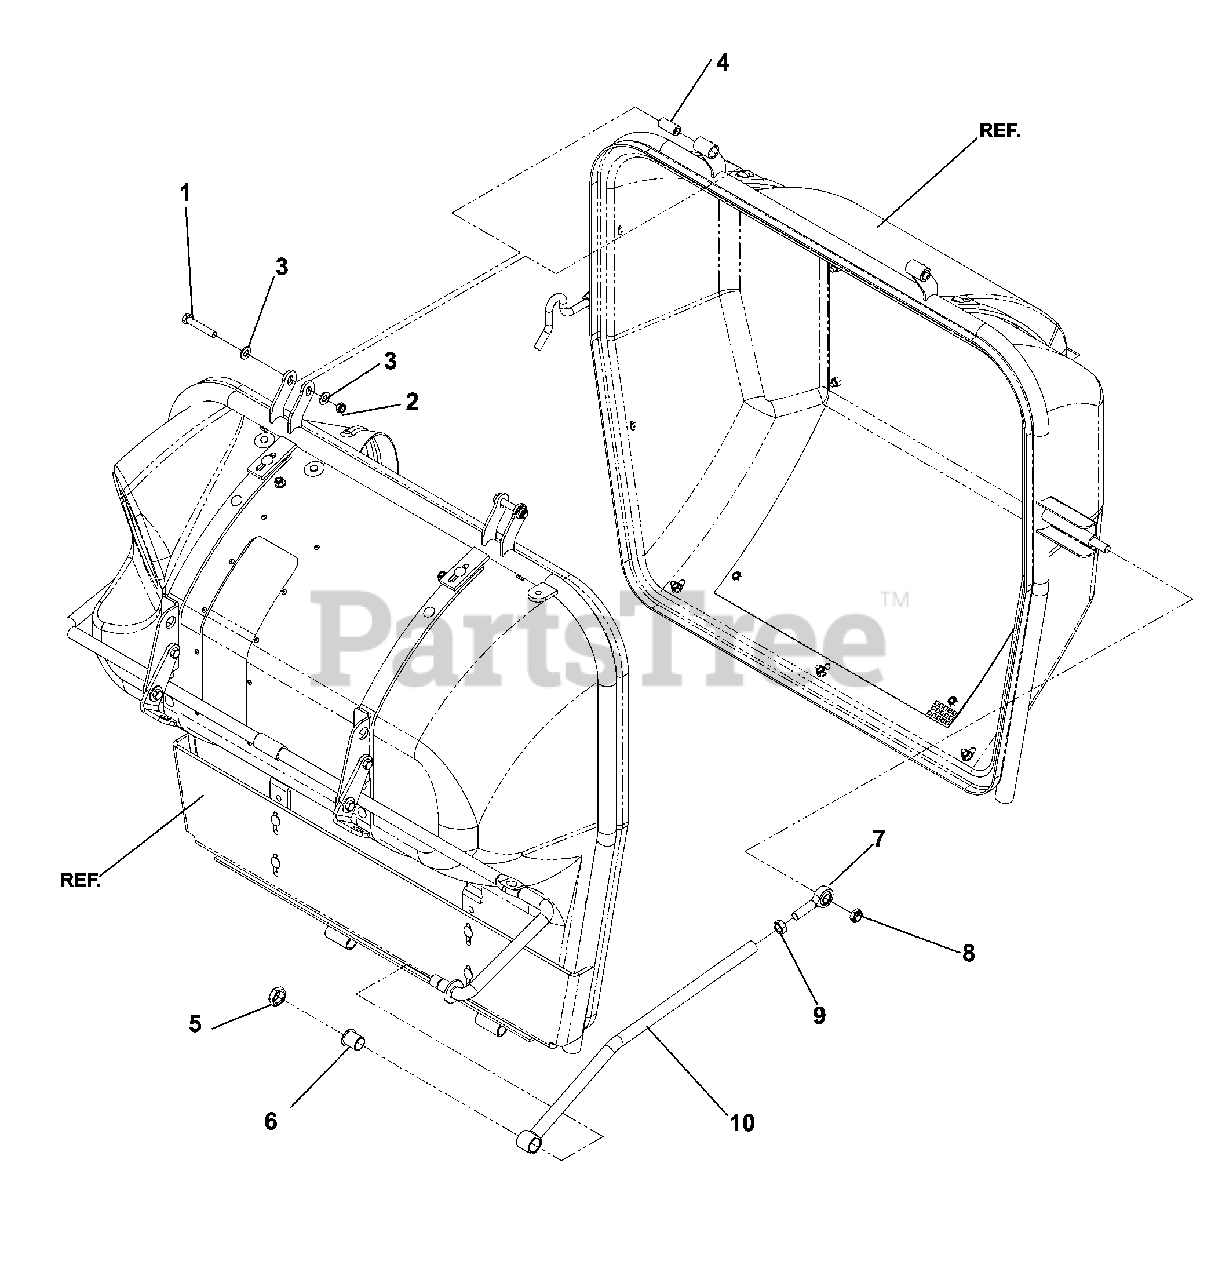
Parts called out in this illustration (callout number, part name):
1	HCS 3/8C X 2 1/4
2	NUT HEX 3/8-16 NYLON, THIN
3	WASHER 3/8 SAE FLAT
4	BUSHING
5	NUT 5/16 NYLOC
6	BUSHING
7	ROD END
8	NUT, 1/2-13 THIN PROF NYL
9	NUT 1/2 HEX JAM
10	LIFT LINK WLDT.
